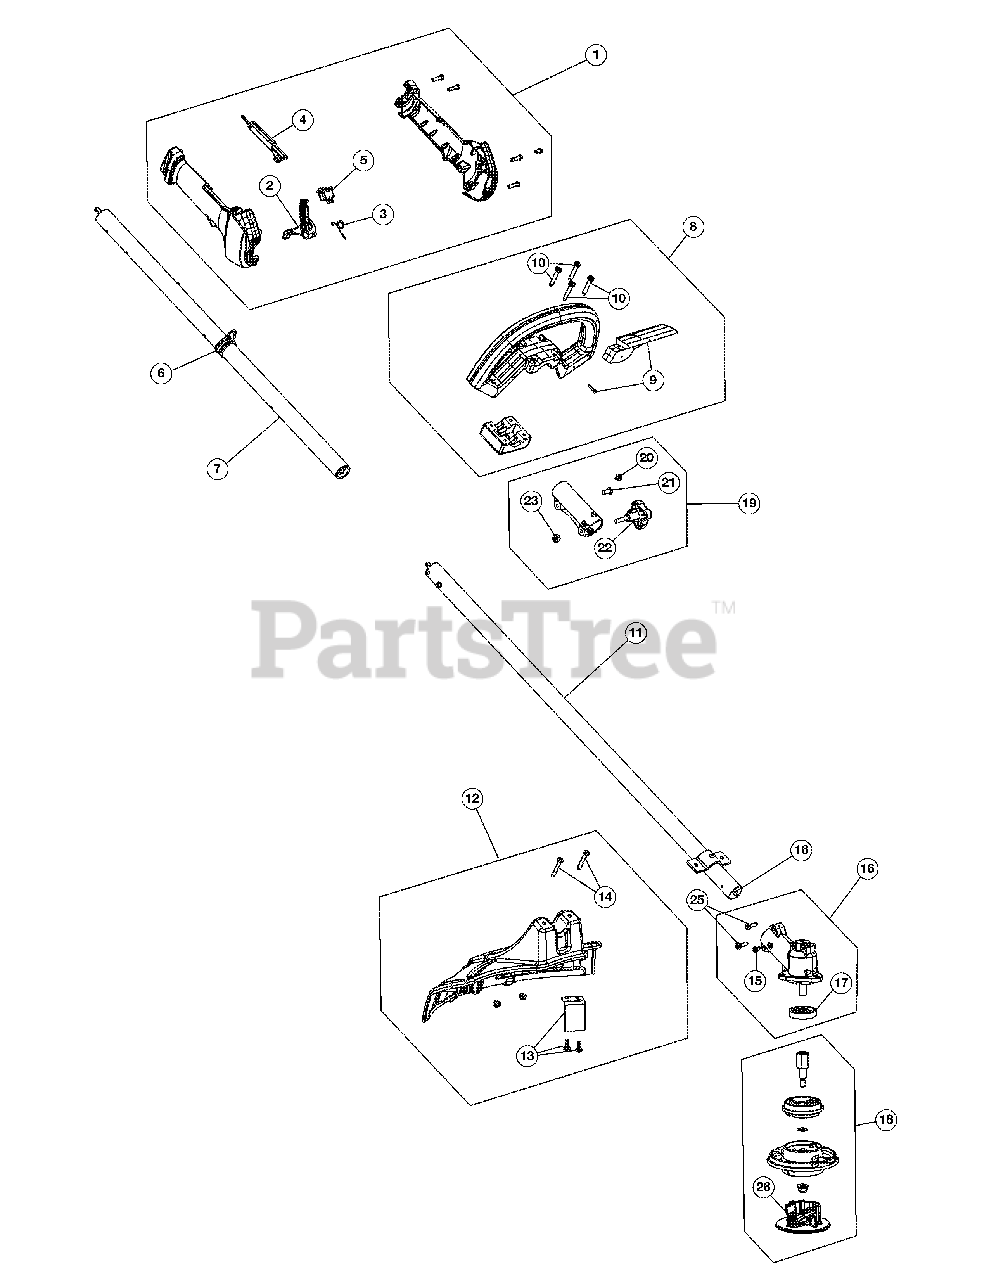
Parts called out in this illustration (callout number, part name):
1	Throttle Housing Assembly (Incl. Ref No. 2-5)
2	Throttle Trigger
3	Spring
4	Throttle Lock-out
6	Shoulder Strap Clip
7	Upper Drive Shaft Housing Assembly
8	D-Handle Assembly (Incl. Ref No. 9 & 10)
9	Barrier Bar Assembly
11	Lower Drive Shaft Housing Assembly
12	Shield Assembly (Incl. Ref No. 13 & 14)
13	Blade Assembly
15	Anti-Rotation Screw
16	Gear Box (Incl. Ref No. 15, 17 & 25)
17	Gear Box Spacer
18	Cutting Head Assembly (Incl. Ref No. 26)
19	Split Boom Coupler (Incl. Ref No. 20-23)
22	Adjustment Knob
23	Knob Retaining Nut
24	Lower Flexible Drive Shaft
25	Gear Box Screw
26	Cutting Head Cap
